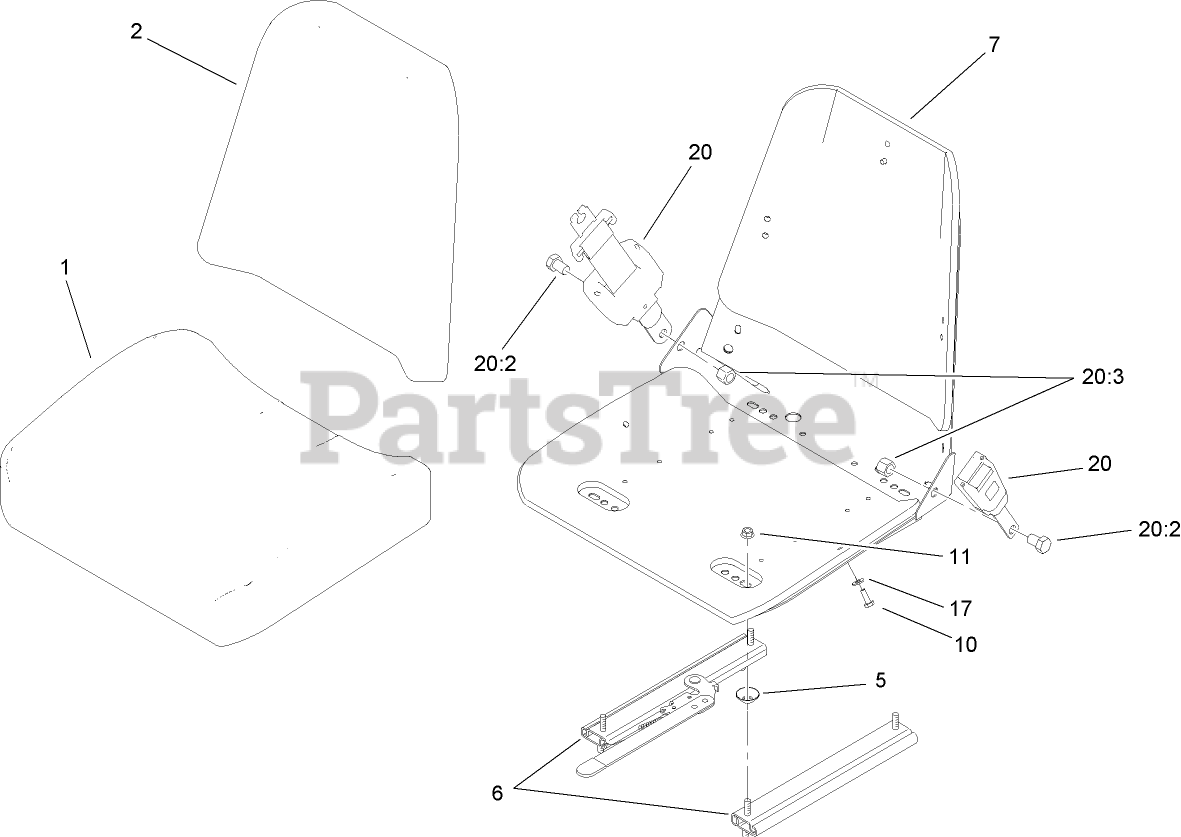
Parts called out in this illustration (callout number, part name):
1	CUSHION-SEAT, BOTTOM
2	CUSHION-SEAT, BACK
5	SPACER-TRACK
6	TRACK-SEAT
7	FRAME-SEAT
10	SCREW-HH
11	NUT-HF
17	WASHER-FLAT
20	RETRACTABLE SEATBELT KIT
20:2	SCREW-HH
20:3	NUT-LOCK
